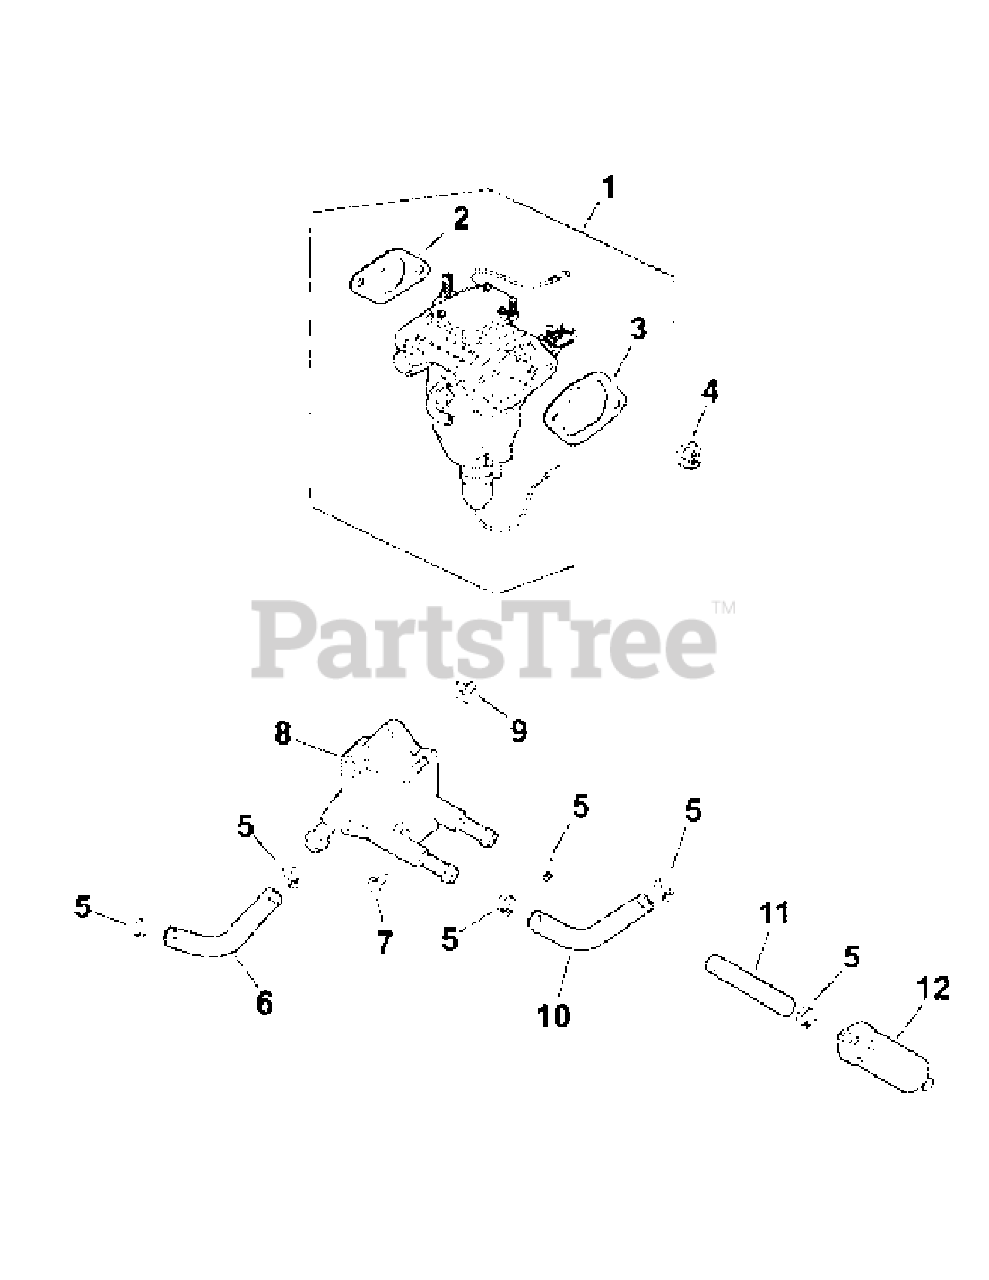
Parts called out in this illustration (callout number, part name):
1	Carburetor Kit
2	Carburetor Gasket
3	Air Cleaner Base Gasket
4	Hex Flange Nut
6	Fuel Line 11"
7	Hex Cap Screw
10	Fuel Line 13"
11	Fuel Line 3.5"
